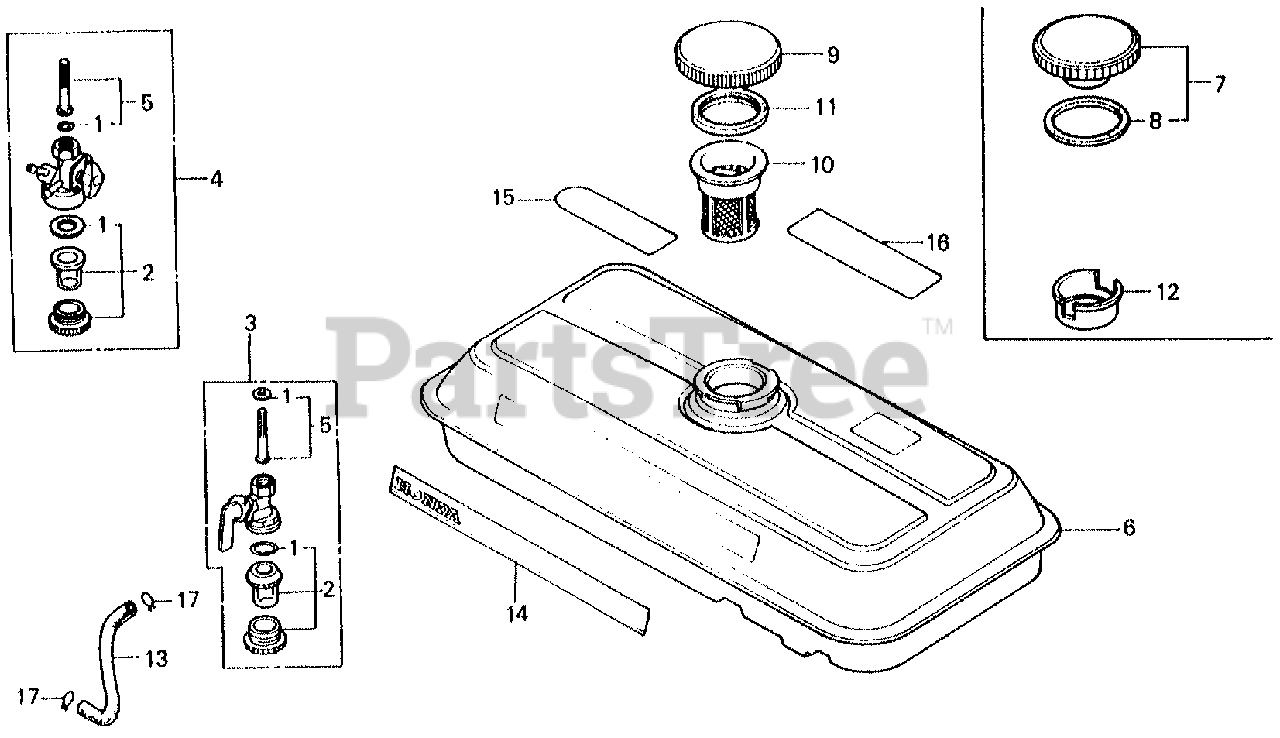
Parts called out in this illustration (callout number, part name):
1	GASKET SET, VALVE
2	CUP SET, FUEL STRAINER
3	PETCOCK ASSY.
4	PETCOCK ASSY.
5	SCREEN SET
6	TANK, FUEL *NH31* (MCKINLEY WHITE)
7	CAP, FUEL FILLER
8	GASKET, FUEL FILLER CAP
9	CAP, FUEL TANK (NOT AVAILABLE)
10	FILTER, FUEL
11	GASKET, FUEL FILTER (NOT AVAILABLE)
12	HOLDER, FUEL FILTER
13	TUBE, FUEL (NOT AVAILABLE)
15	MARK A, CAUTION
16	MARK, CAUTION (CO)(ENGLISH/FRENCH)(SPANISH)
17	CLIP, TUBE (B8)
